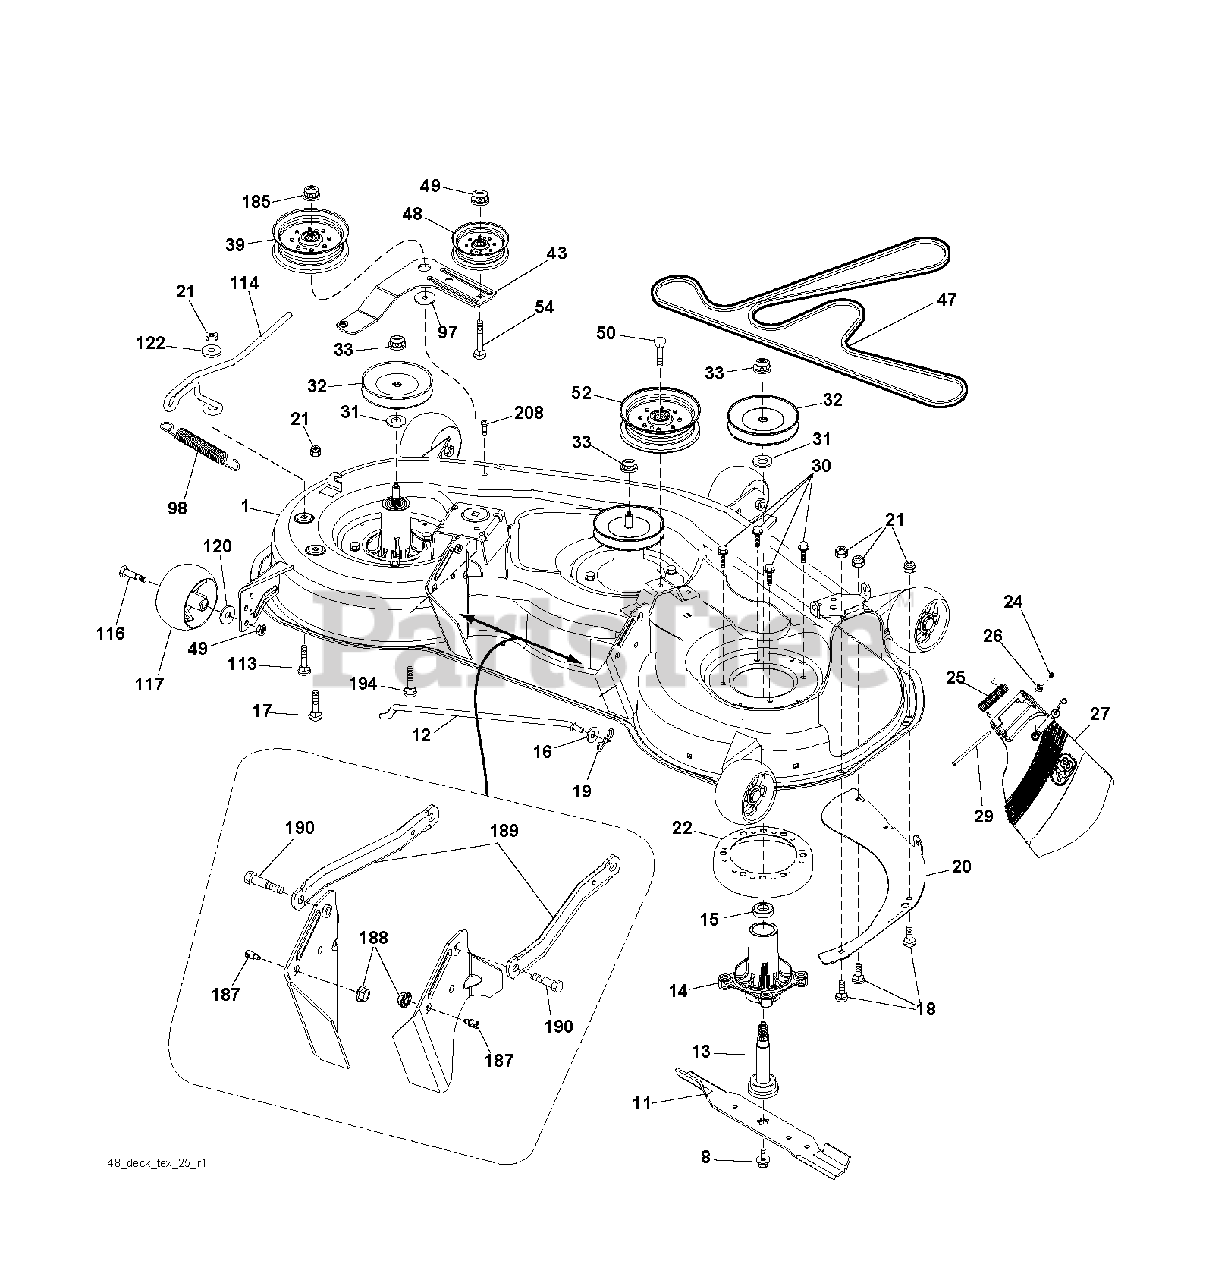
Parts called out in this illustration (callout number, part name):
1	DECK WELDMENT
8	BOLT.WASHER.ASM.7/16-2
11	48" HI-LIFT BLADE
12	ROD.ANTI.SWAY.48/54"K4
13	SHAFT ASM MANDREL
14	HOUSING MANDREL
16	WASHER
17	BOLT
18	BOLT
19	PIN.COTTER.5/16.BOW TI
20	BAFFLE, VORTEX MWR
21	LOCKNUT
22	STRIPPER, MWR ROUND
24	CAP-SLEEVE LT
25	SPRING, TORSION
26	NUT PUSH M
29	ROD.HINGE
30	SCREW, WASHER HEAD
31	WASHER.SPACER.MANDREL
32	PULLEY MANDREL
33	NUT.FLANGE.LOCK.TOP
39	PULLEY.IDLER.4.50/HUB SPECIAL
43	ARM.IDLER
46	SCREW.1/4-20X5/8
47	BELT.DRIVE.DECK
48	PULLEY.IDLER.48"PRIMARY
49	NUT LOCK FLG 3/8-16 UNC
50	SCREW TT 3/8-16X2-1/4 UNC
52	PULLEY.IDLER.2006
54	BOLT.3/8-16X1.50
98	SPRING, DECK DRIVE
114	ROD.TENSION.RELIEF.TEX
116	BOLT.SHOULDER.3/8-16X3-5/8
117	WHEEL. GUAGE RALLY
122	BUSHING.RELIEF.TENSION
185	NUT.LOCK.FLANGE.7/16
187	STUD.FASTNER.W/ANTI-ROTATE
188	NUT LOCK HEX FLANGE 5/16-18
189	ARM.SUSPENSION.MOWER
190	BOLT.SHOULDER
194	BOLT.CARR.SQNK.7/16
208	SCREW 3/8-16X1/2
244	PALNUT 1/4
